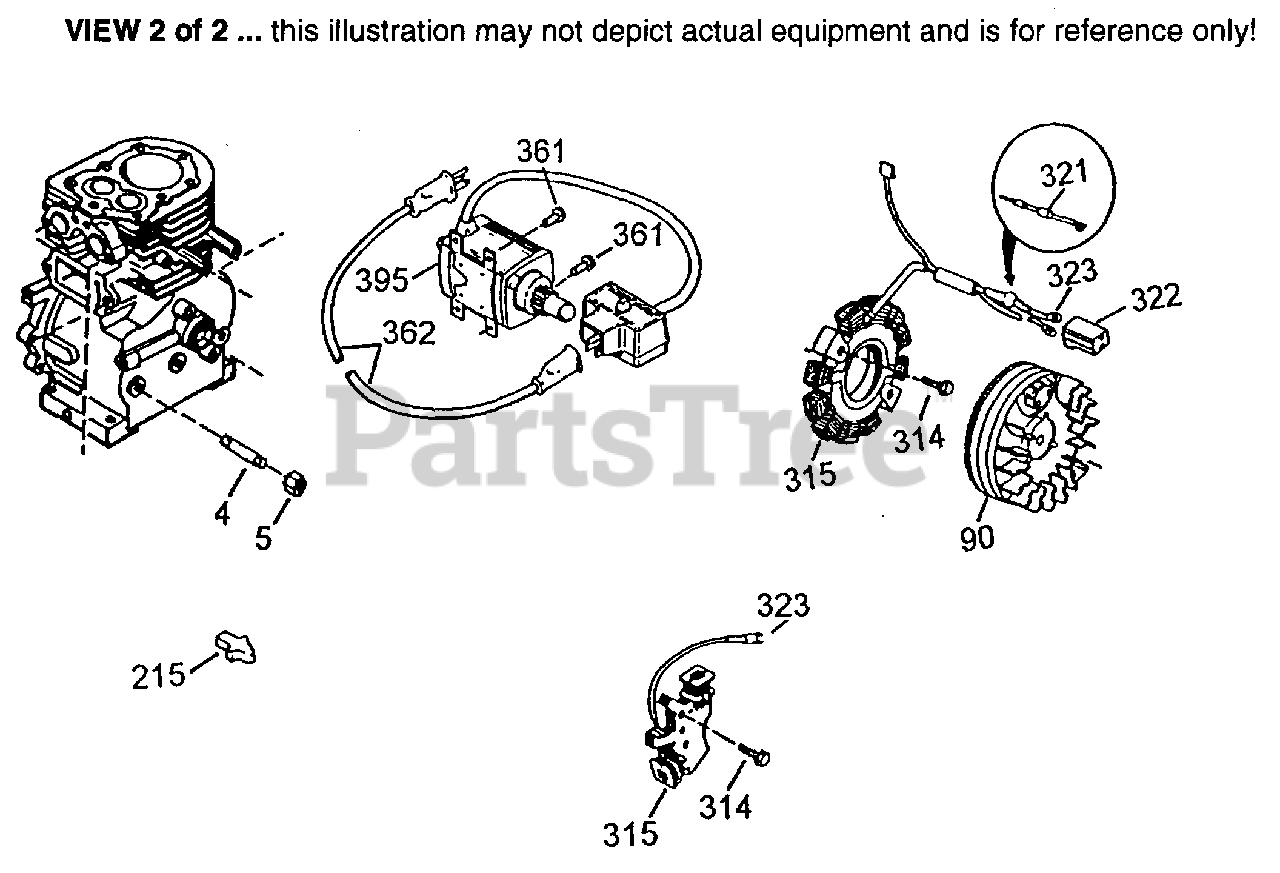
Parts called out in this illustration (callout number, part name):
4	Oil Drain Extension
5	Extension Cap
90	Flywheel
215	Control Knob
264A	Screw, 5/16-18 x 3/4"
286	Starter Screen
370A	Control Decal
370B	Warning Decal
370C	Primer Decal
370D	Choke Decal
